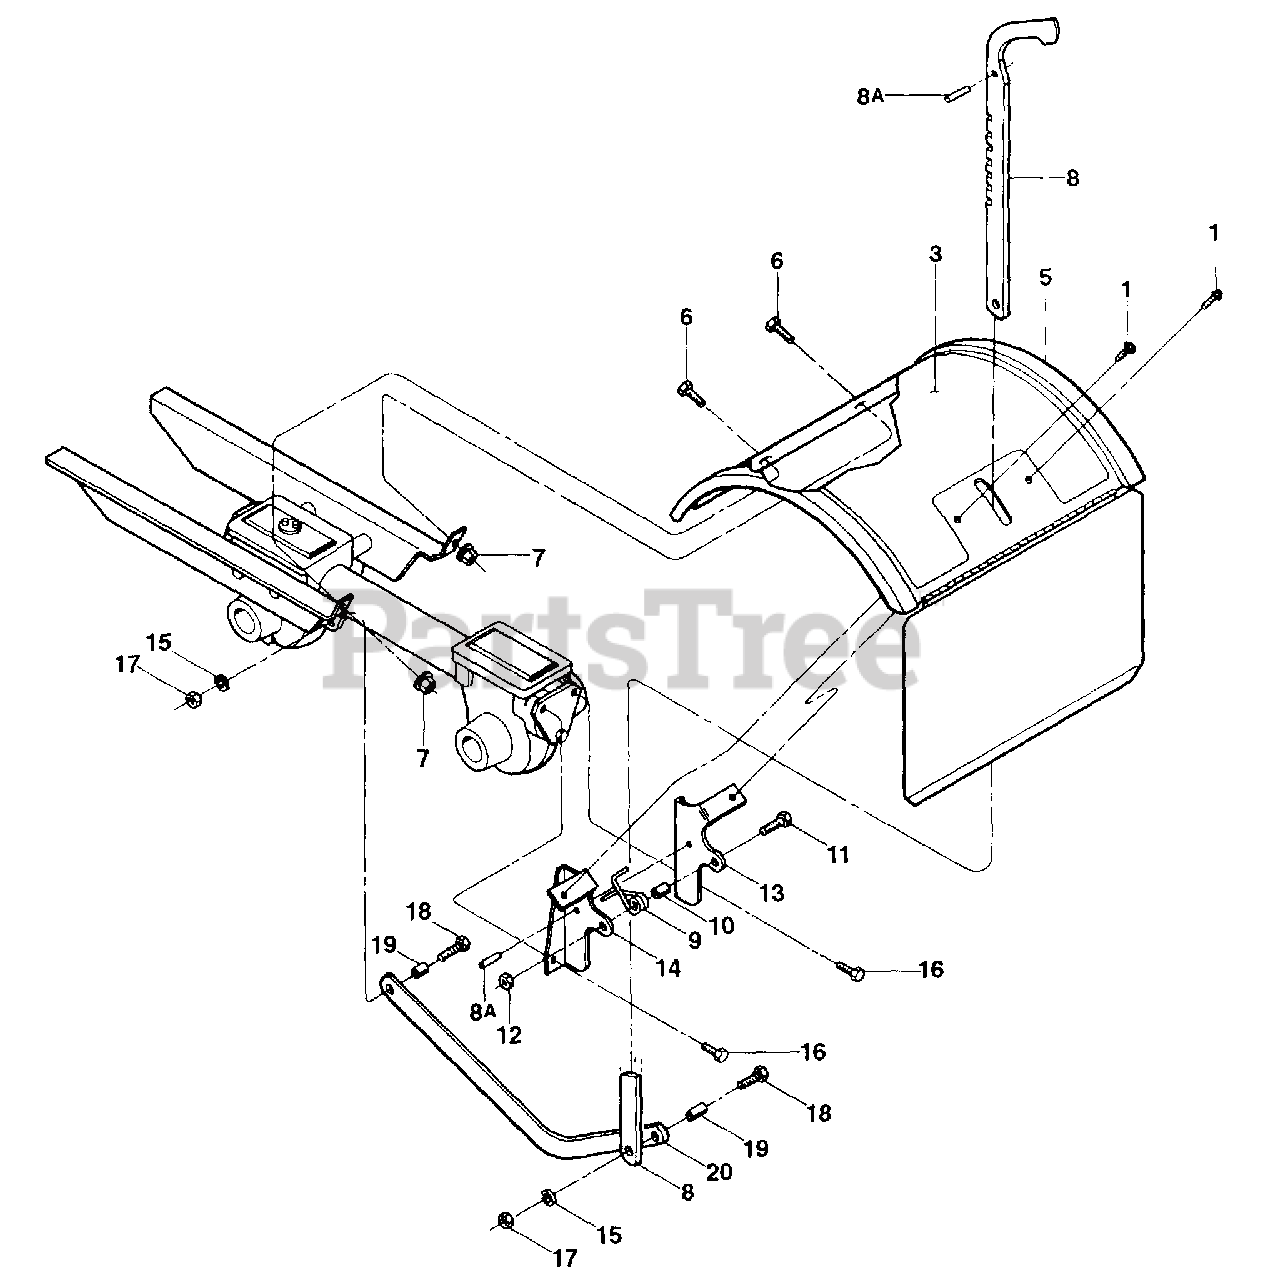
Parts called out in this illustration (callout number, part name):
1	Bolt-Flanged Hd, Self-Tapping, 1/4-20 x 1/2"
3	Decal-Hood
5	Tine Hood
6	Bolt-Hex Hd, 5/16-18 x 1/2"
7	Nut-Flange Lock, 5/16-18
8	Depth Regulator Lever
8A	Spiral Pin
9	Spring-Depth Regulator
10	Spacer
11	Bolt-Hex Hd, 1/4-20 x 1"
12	Locknut-Hex Hd, 1/4-20
13	Bracket-Hood, Right Hand
14	Bracket-Hood, Left Hand
15	Lockwasher, 5/16"
16	Bolt-Flanged Hd, 5/1 6-18 x 1"
17	Nut-Hex Hd, 5/16-18
18	Bolt-Hex Hd, 5/1 6-18 x 1-1/4"
19	Bushing-Drag Bar
20	Drag Bar
